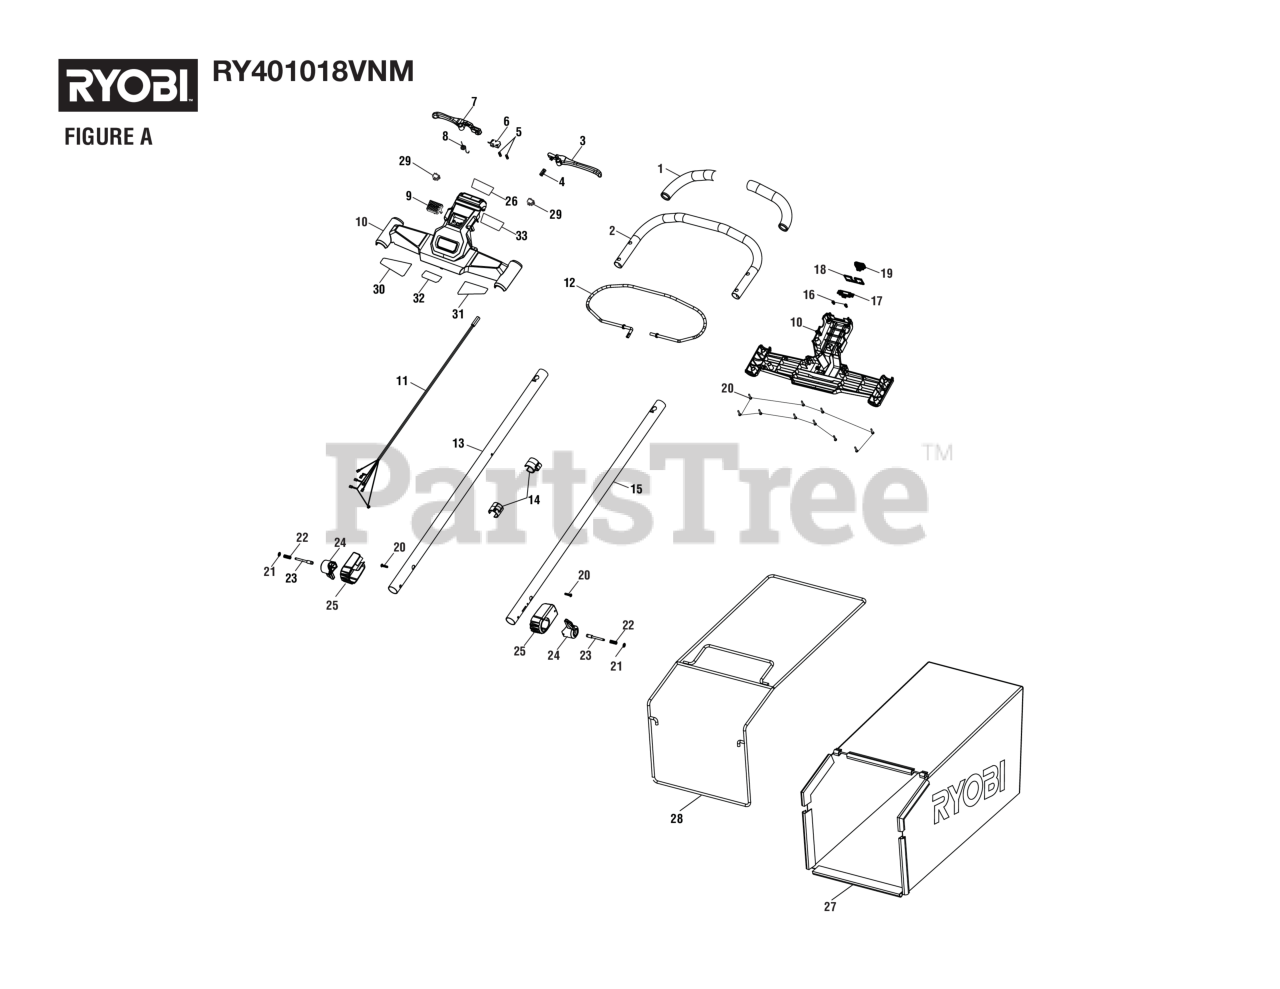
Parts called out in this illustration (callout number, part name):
3	Trigger Left
4	Compression Spring
6	On/Off Switch
6	Micro On/Off Switch (6A)
7	Trigger (Right)
8	Bail Reset Spring
9	Start Button
10	Upper Handle Assembly
11	Wire Cord Assembly
13	Lower Tube
14	Cord Retainer
15	Lower Tube
16	Screw (M3 x 8 mm, Pan Hd., Pan Hd)
17	Variable Switch
18	Dust Shield
19	Thumb Pad
20	Screw (M4 x 18 mm, T20 Torx Pan Hd.)
21	Retaining Ring
22	Compression Spring
23	Detent Pin
24	Adjustment Knob
25	Adjustment Knob Bushing
26	Handle Speed Label
27	Grass Catcher
28	Grass Catcher Frame
30	Upper Handle Label (Left)
31	Logo Label
32	Upper Handle Label (Right)
33	Starting Label
